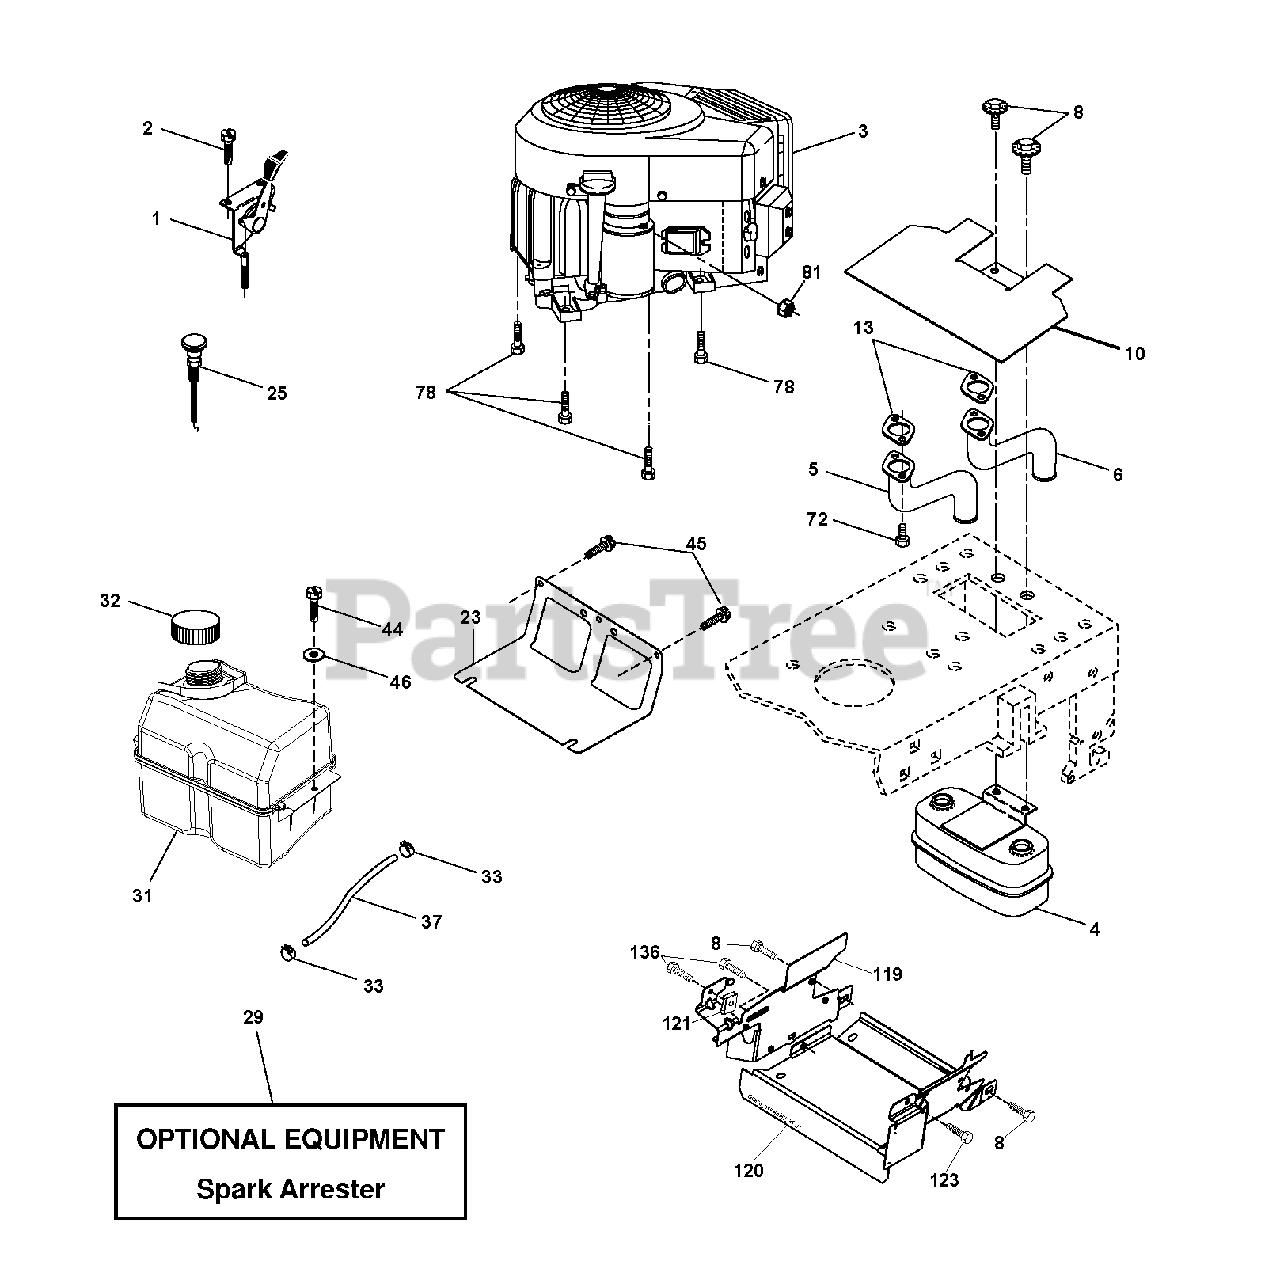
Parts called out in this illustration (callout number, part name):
1	CONTROL, THROTTLE
2	SCREW
4	MUFFLER.TWIN.CYL.LOW.TONE
5	EXHAUST TUBE RH
6	TUBE MANIFOLD LH
8	BOLT, 5/16-18 X 1 3/4
10	RP SHIELD HEAT MUFFLER
13	GASKET.MUFFLER
23	SHEILD.BROWNING.DBR.GUARD
29	ARRESTER SPARK (OPTIONAL)
32	CAP ASM.FUEL.2.25"FR.
33	HOSE CLAMP
37	LINE.FUEL.20
44	SCREW HEXWSHR 1/4-20X3/4
45	SCREW, 3/8-16X3/4
72	SCREW.SOCKET.HEAD.5/16-18
78	SCREW.3/8-16
81	NUT
123	SCREW, 5/16-18 X 1/2
136	SCREW.1/4-20X5/8
